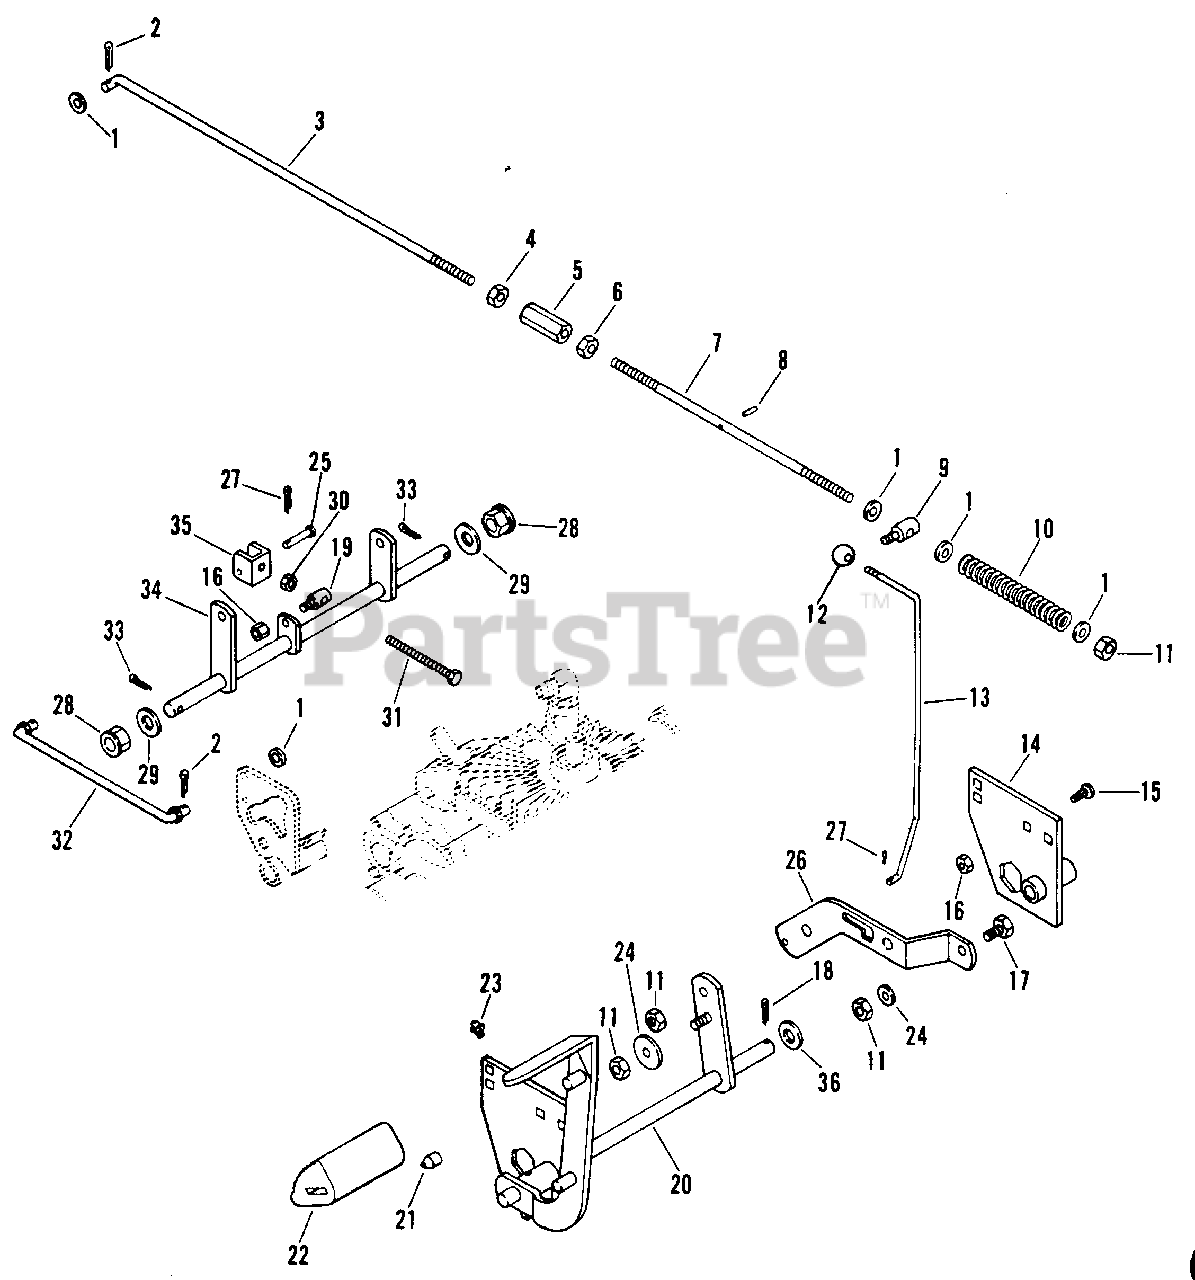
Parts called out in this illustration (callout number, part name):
1	Washer, Flat .406 x .812 x .065
2	Pin, Cotter 3/32 x .75
3	Rear Brake Rod
4	Nut, Hex 3/8-16 L.H.
5	Nut, Coupling
6	Nut, Hex 3/8-16
7	Front Brake Rod
8	Pin, Spring .125 x .750
9	Pivot
10	Spring, Compression
11	Nut, Lock 3/8-16
12	Knob
13	Rod, Brake Lock
14	Bracket
15	Bolt, Carriage 5/16-18 x .75
16	Nut, Lock 5/16-18
17	Bolt, Hex 3/8-16 x 1.00
18	Pin, Cotter 5/32 x 1.50
19	Pivot, Rod
20	Weldment, Brake Shaft
21	Grip
22	Cover, Pedal
23	Spin, Drive Zerk Fitting
24	Washer, Flat .375 x 1.125 x .065
25	Pin, Clevis .250 x 1.500
26	Arm, Park
27	Pin, Cotter 1/16 x .75
28	Bush., .625 x .875 x .750
29	Bearing, Thrust Race
30	Nut, Lock 5/16-18
31	Bolt, Hex 5/16-18 x 3.50
32	Rod, Neutral
33	Pin, Cotter .156 x 1.50
34	Shaft, Brake
35	Clevis
36	Washer, Flat .656 x 1.312 x .095
